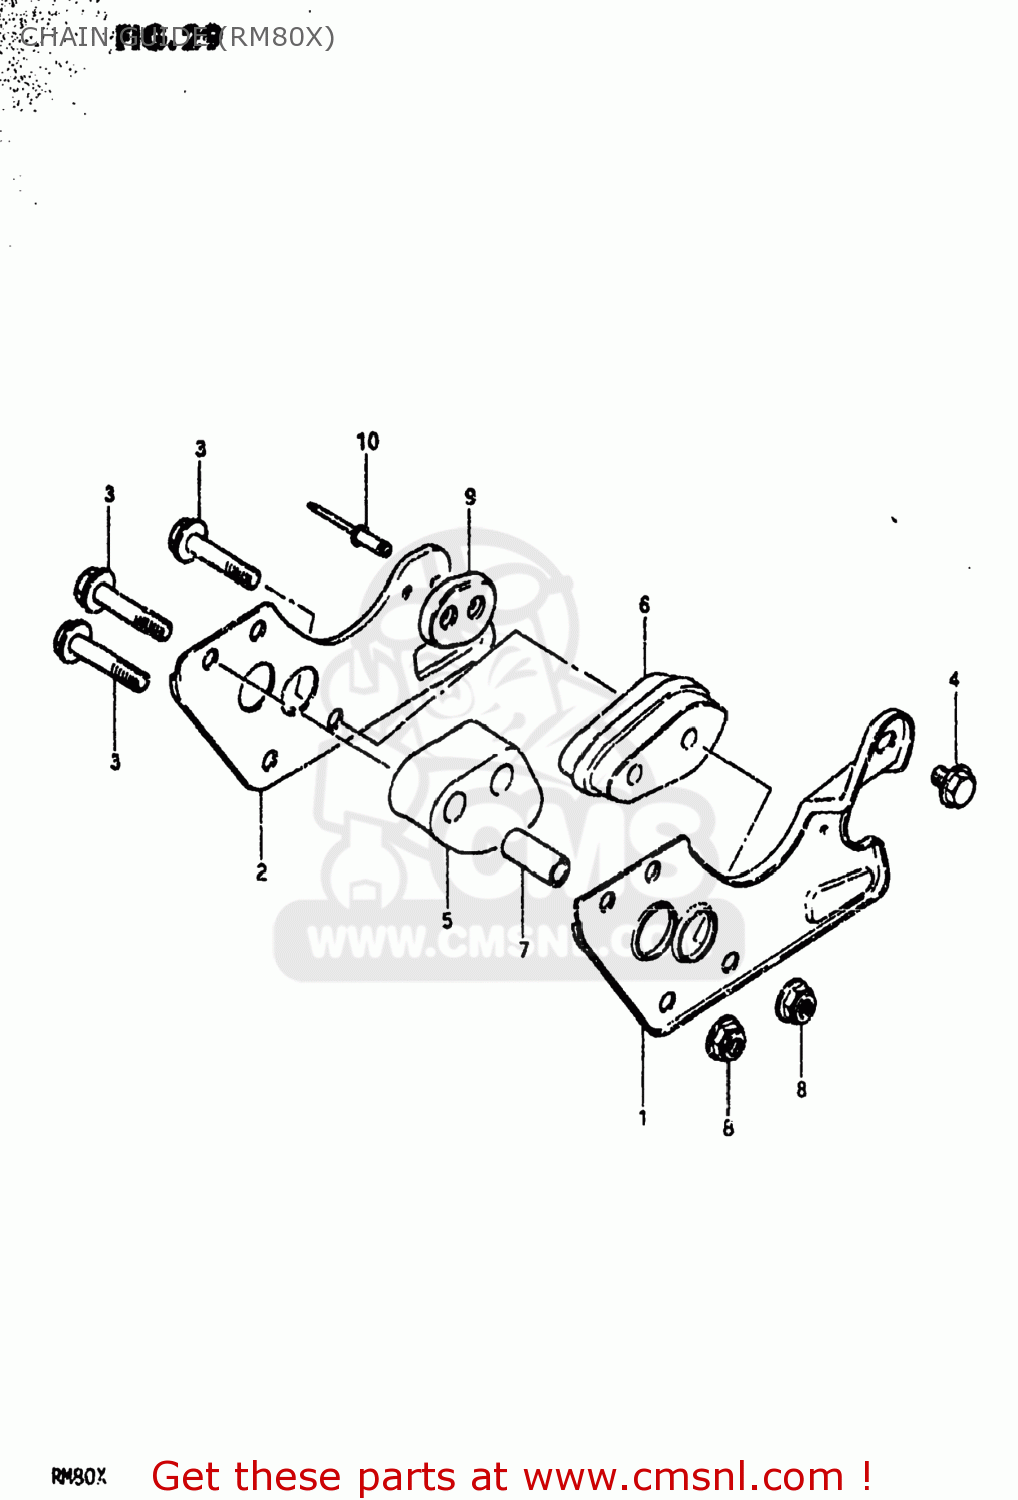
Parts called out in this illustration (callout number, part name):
1	GUIDE,CHAIN,OUTER
2	GUIDE,CHAIN,INNER
3	BOLT 6X35
4	BOLT
5	ROLLER,CHAIN GUIDE
6	DEFENSE,CHAIN GUIDE
7	SPACER(6.8X10X24.2)
8	NUT
9	PAD,DRIVE CHAIN GUIDE
10	RIVET
